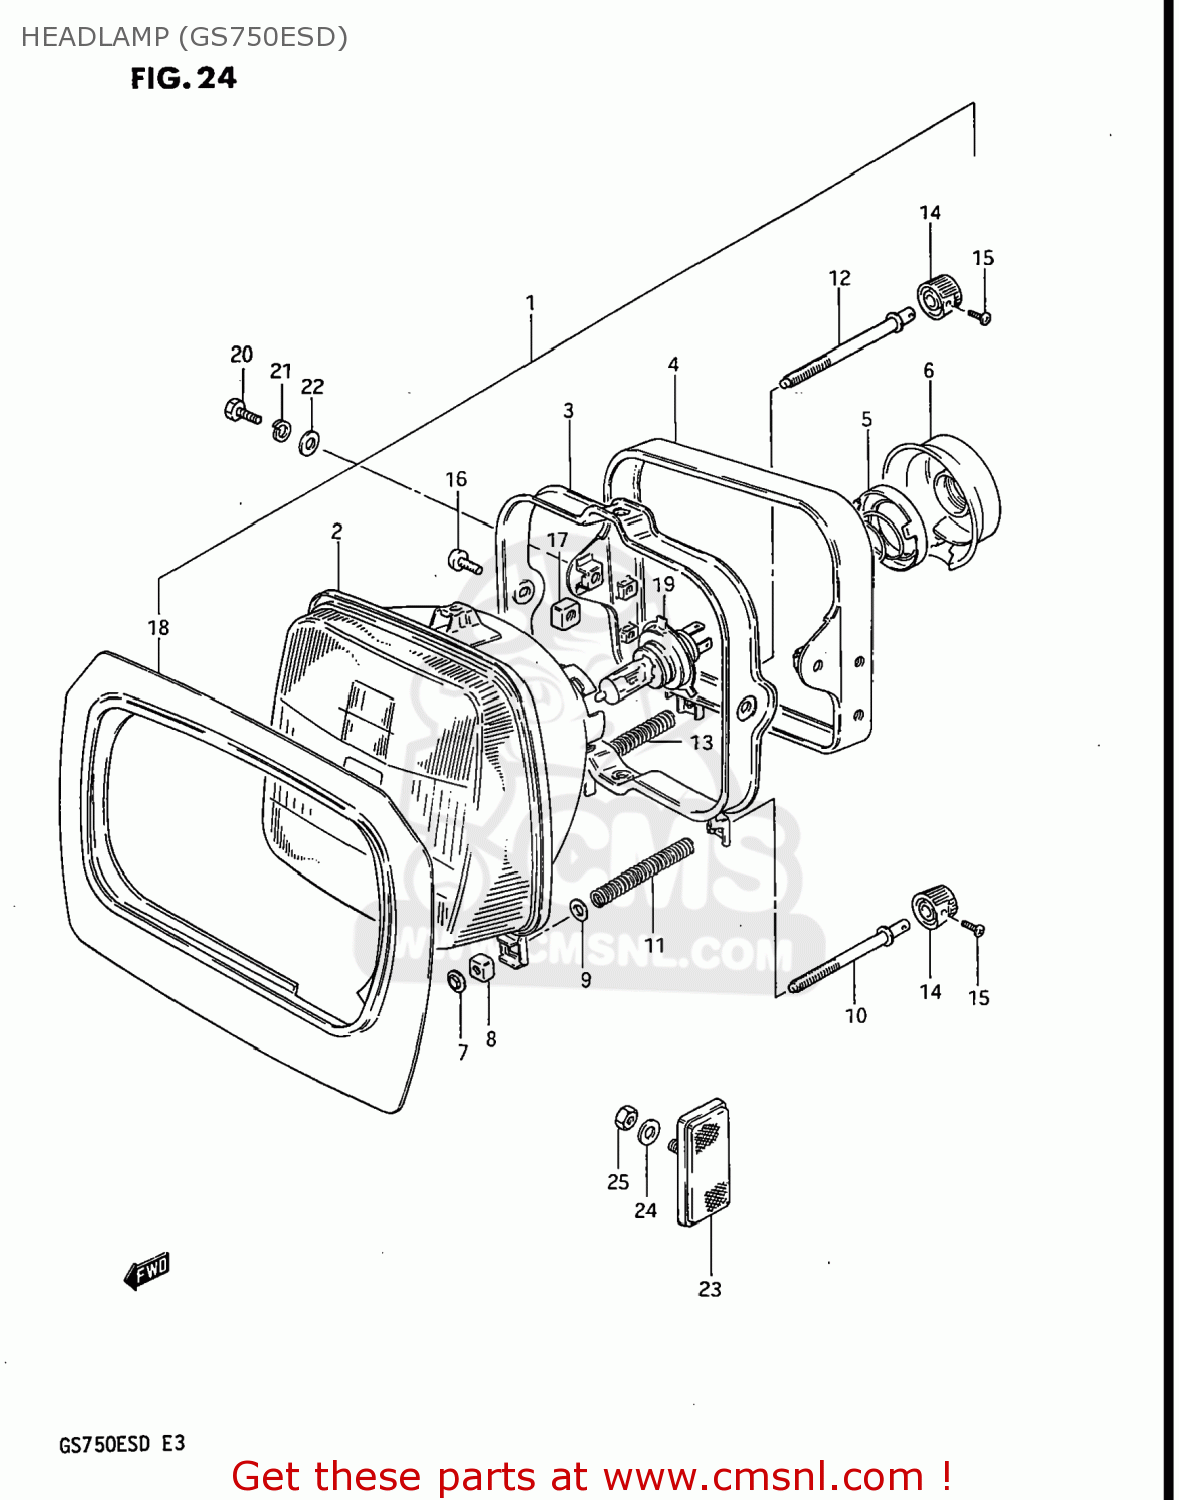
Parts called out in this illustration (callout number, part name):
1	LAMP ASSEMBLY,HEAD
2	LAMP UNIT
3	RING,MOUNTING
4	HOUSING,LAMP UNIT
5	HOLDER
6	COVER,HEADLAMP SOCKET
7	NUT,HEADLAMP ADJUSTER
8	NUT,HEADLAMP ADJUSTER
9	WASHER
10	SCREW,HEADLAMP ADJUST
11	SPRING
12	SCREW,ADJUSTING
13	SPRING
14	KNOB,ADJUSTER
15	SCREW
16	SCREW
17	NUT
18	SHADE
19	BULB(12V60/55W,H4)
20	BOLT
21	LOCK WASHER
22	WASHER
23	REFLEX REFLECTOR ASSEMBLY
24	WASHER
25	NUT
